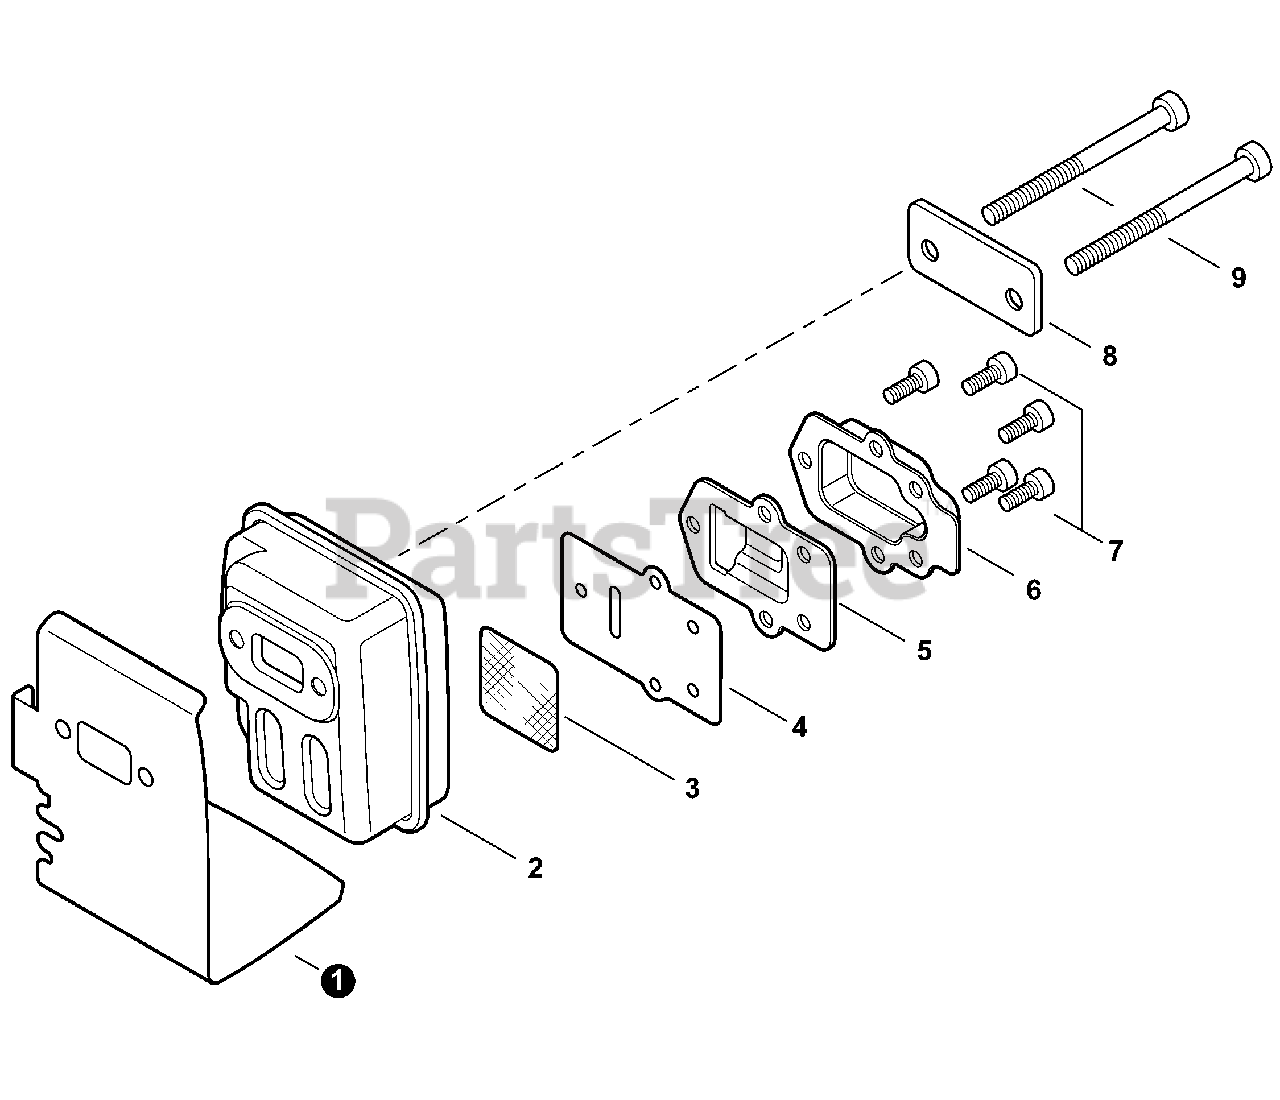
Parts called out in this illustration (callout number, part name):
1	HEAT SHIELD, EXHAUST
2	MUFFLER
3	SCREEN, SPARK ARRESTER
4	GASKET, EXHAUST
5	GUIDE, EXHAUST
6	DEFLECTOR, EXHAUST
7	SCREW 4×10
8	PLATE, EYE
9	BOLT 5×55
